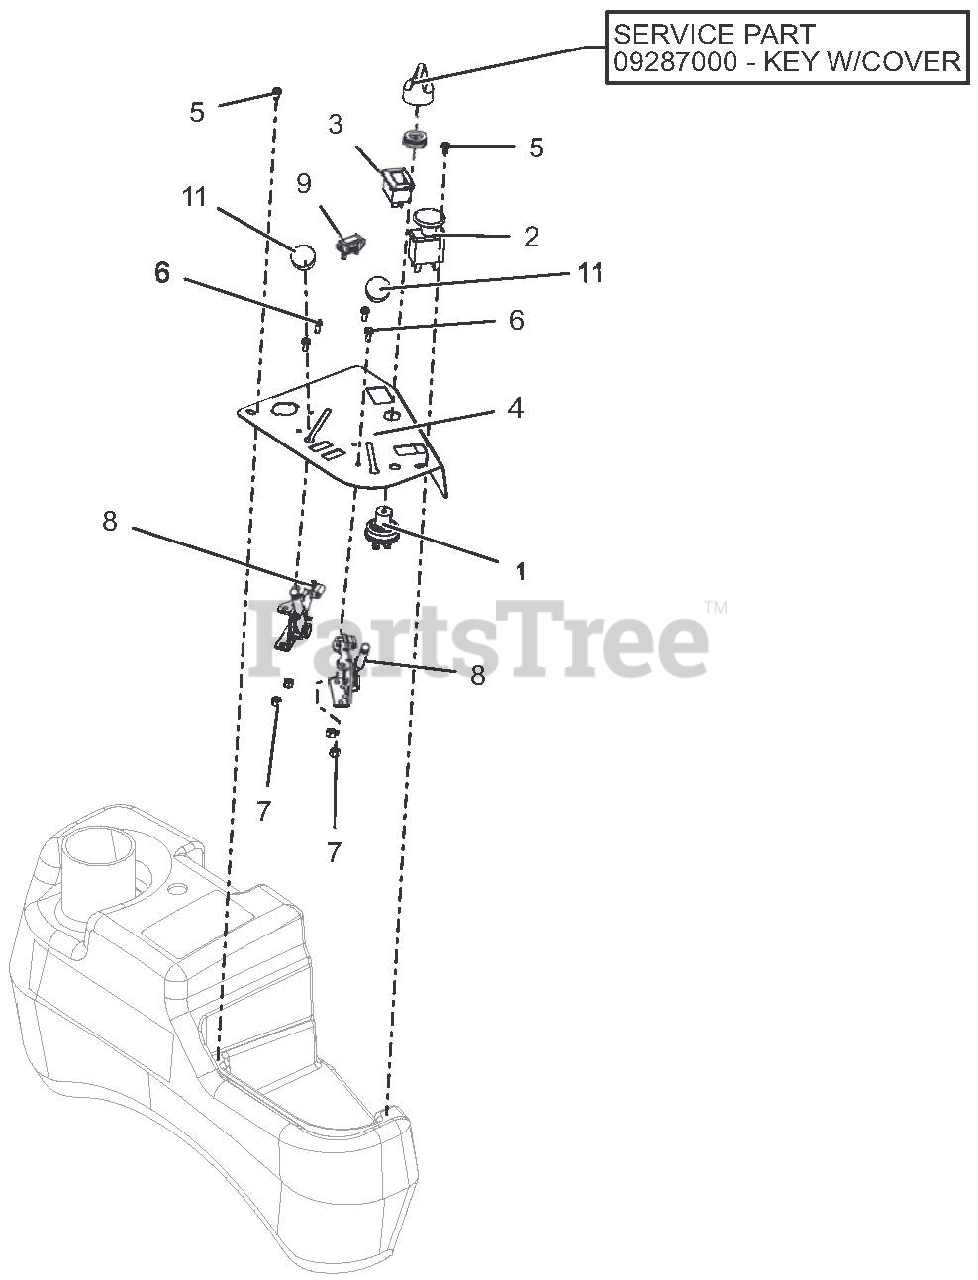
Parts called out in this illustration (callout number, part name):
1	SWITCH, IGNITION
2	SWITCH, CLUTCH
3	METER, HOUR W/MAINTENANCE
4	PANEL, CONTROL - PROTURN 100
5	SCR-MCH 10-24X.38 HWHSTAINLESS
6	@SCR-MCH 10-24X.50 HWH YWZC
7	NUT-LK-NYL #10-24 YWZC
8	CABLE, PRO-CONTROL THROTTLE
9	LIGHT, INDICATOR
11	KNOB, CONTROL BLACK .38-16X.50
12	KEY W/COVER
